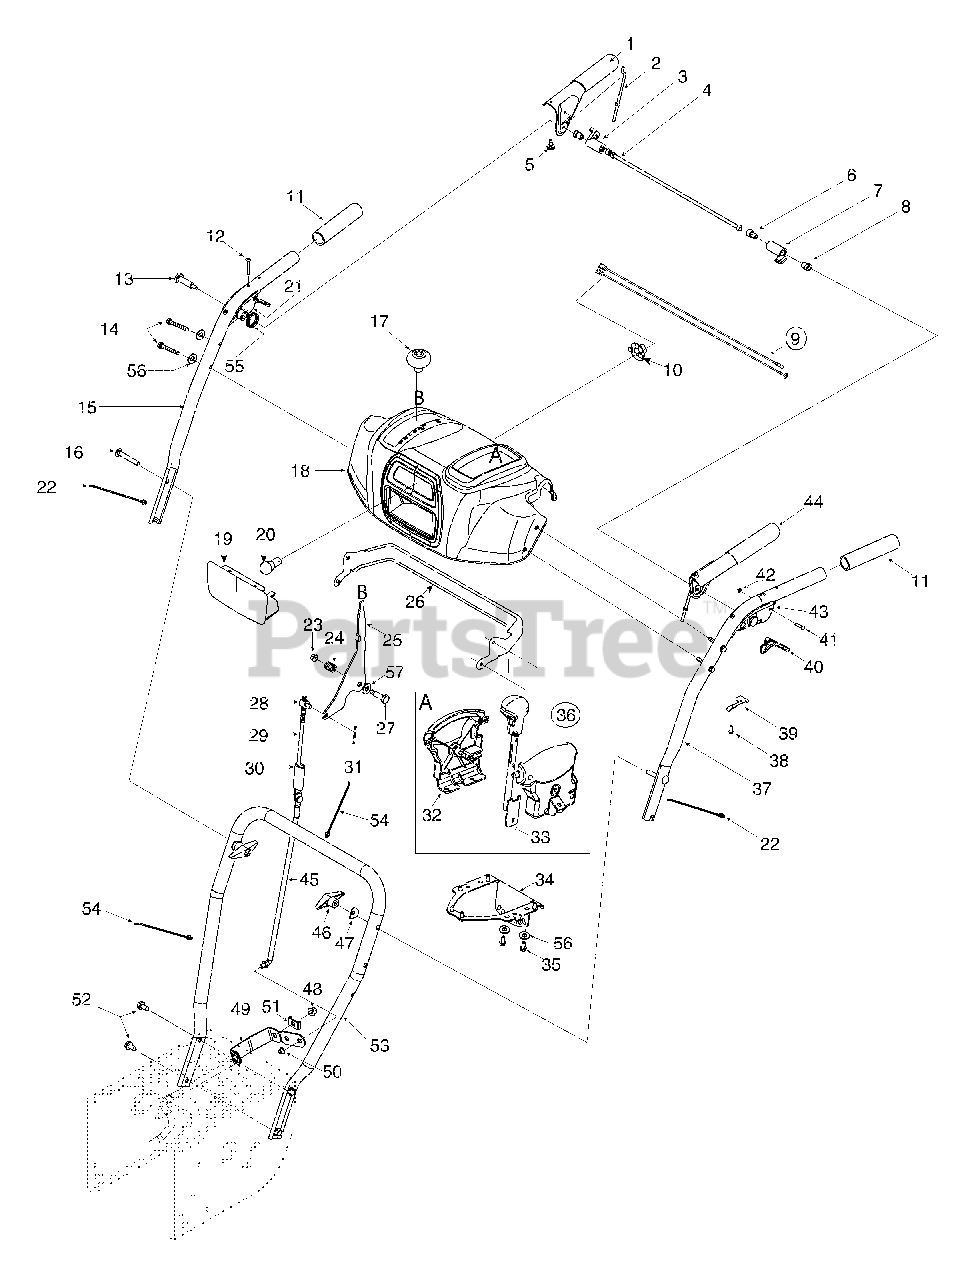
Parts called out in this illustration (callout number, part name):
2	Cable Z Fitting
3	Lock Plate
4	Pivot Rod
5	Rubber Bumper
6	Screw, 1/4-20 x.375
7	Clutch Lock Cam
8	Shoulder Nut, 1/4-20
9	Wire Harness
10	Light Socket
11	Handle Grip
12	Screw, #10-24 x 0.375
13	Shoulder Screw, 1/4-20 x 1.345
14	Screw, 1/4-20 x 1.750
16	Carriage Screw, 5/16-18 x 2.25
17	Shift Knob
18	Handle Panel
19	Lens
20	Lamp
21	Handle Clutch Lock - RH
22	Cable Tie
23	Flange Lock Nut, 1/4-20
24	Compression Spring
28	Ferrule
29	Upper Shift Rod
30	Shift Rod Connector
31	Hairpin Clip
32	Joystick Housing w/Fasteners
33	Knob Assembly w/ Trigger
35	Hi-Lo Screw, 1/4-15 x 0.5
36	4-Way Chute Control(TM) Assembly
38	Screw, #8-16 x 0.50
39	Clutch Lock Spring
40	Steering Control
41	Pin, 3/16
42	E Ring
43	Handle Clutch Lock - LH
45	Lower Shift Control Rod
46	Handle Knob Assembly
47	Saddle Washer
48	Flange Lock Nut, 5/16-18
49	Shift Arm
50	Speed Nut
51	Shift Bracket Spacer
52	AB Screw, 5/16-12 x 0.75
54	Cable Tie
55	Torsion Spring
56	Washer, Flat,.25 x.630 x.0515
57	Washer, Flat,.385 x.870 x.092
